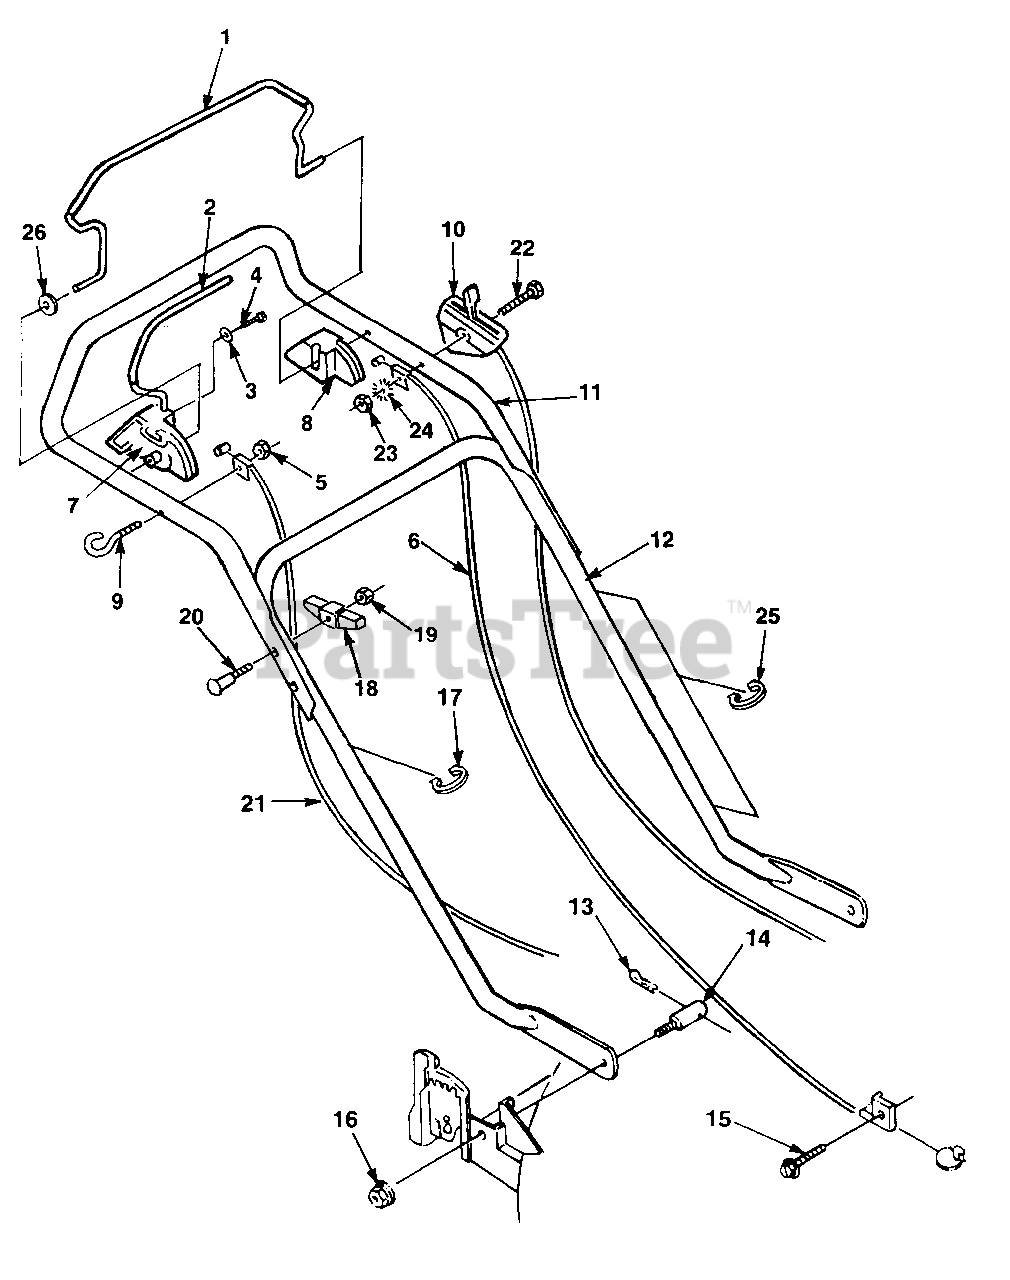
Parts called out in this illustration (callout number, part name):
1	BAIL- Brake control
2	TRACTION- Bail
3	WASHER- Flat (1/4") #10
4	SCREW- Hex hd. (10-16 x 1/2")
5	NUT- Hex (1/4-20)
6	CONTROL- Manual start
7	ACTUATOR- R.H.
8	ACTUATOR- L.H.
9	EYEBOLT- (1/4-20 x 1 3/4")
10	CONTROL- Throttle
11	HANDLE- Upper
12	HANDLE- Lower
13	PIN- Hair
15	SCREW- (10-24 x 1/2")
16	NUT- Flanged (5/16-18)
17	CLAMP- Cable single
18	KNOB- Handle
19	NUT- Hex (5/16 x 18)
20	BOLT- Hdle. joining
21	CABLE- Traction control
22	SCREW- Hex cap
23	NUT- Hex (1/4-20)
24	WASHER- External tooth (1/4")
25	CLAMP- Double
26	WASHER- Flat 5/16"
